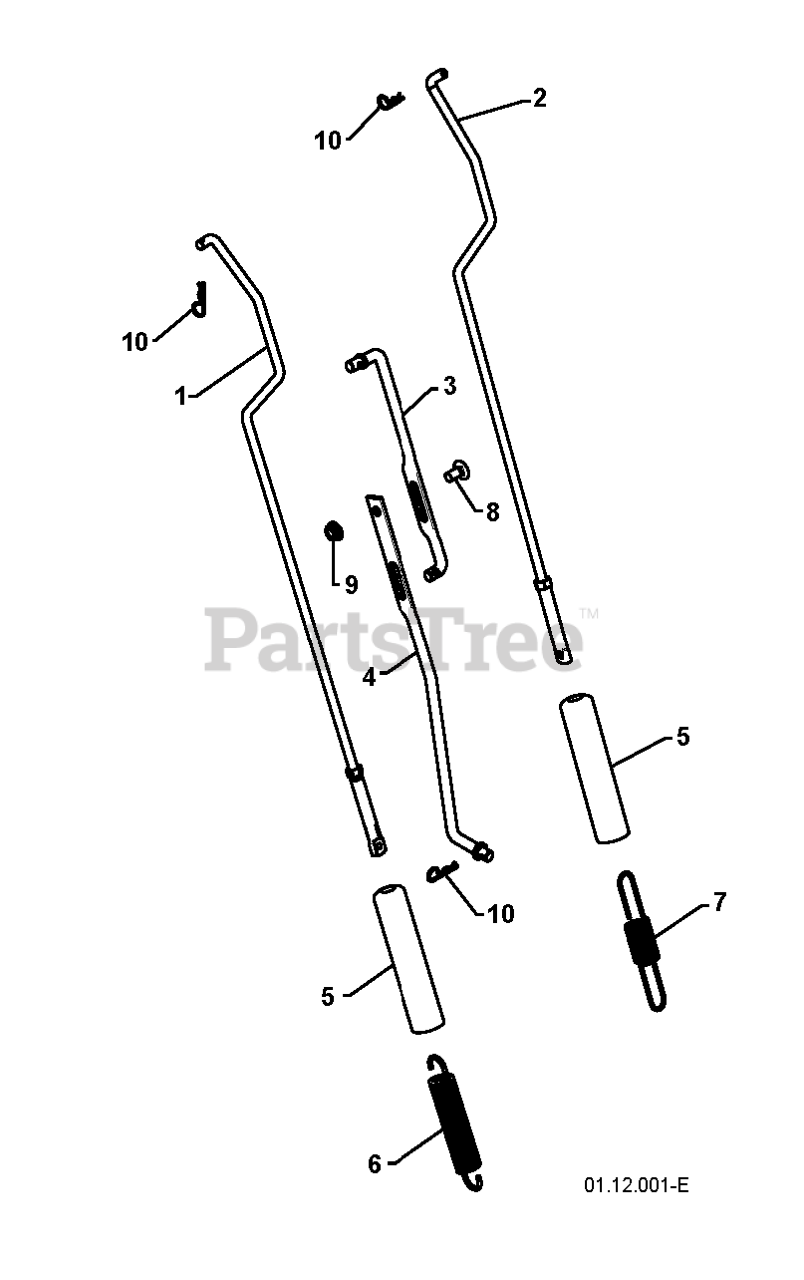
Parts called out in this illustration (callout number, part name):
1	ROD.ASM.IMPELLER
2	ROD.ASM.TRACTION
3	ROD, UPPER SPEED CONTROL
4	ROD, LOWER SPEED CONTROL.SNOW
5	SLEEVE, SPRING
6	SPRING, AUGER CONTROL
7	SPRING, TRACTION DRIVE
8	BOLT
9	NUT.FLANGE.5/16
10	SPRING RETAINER
